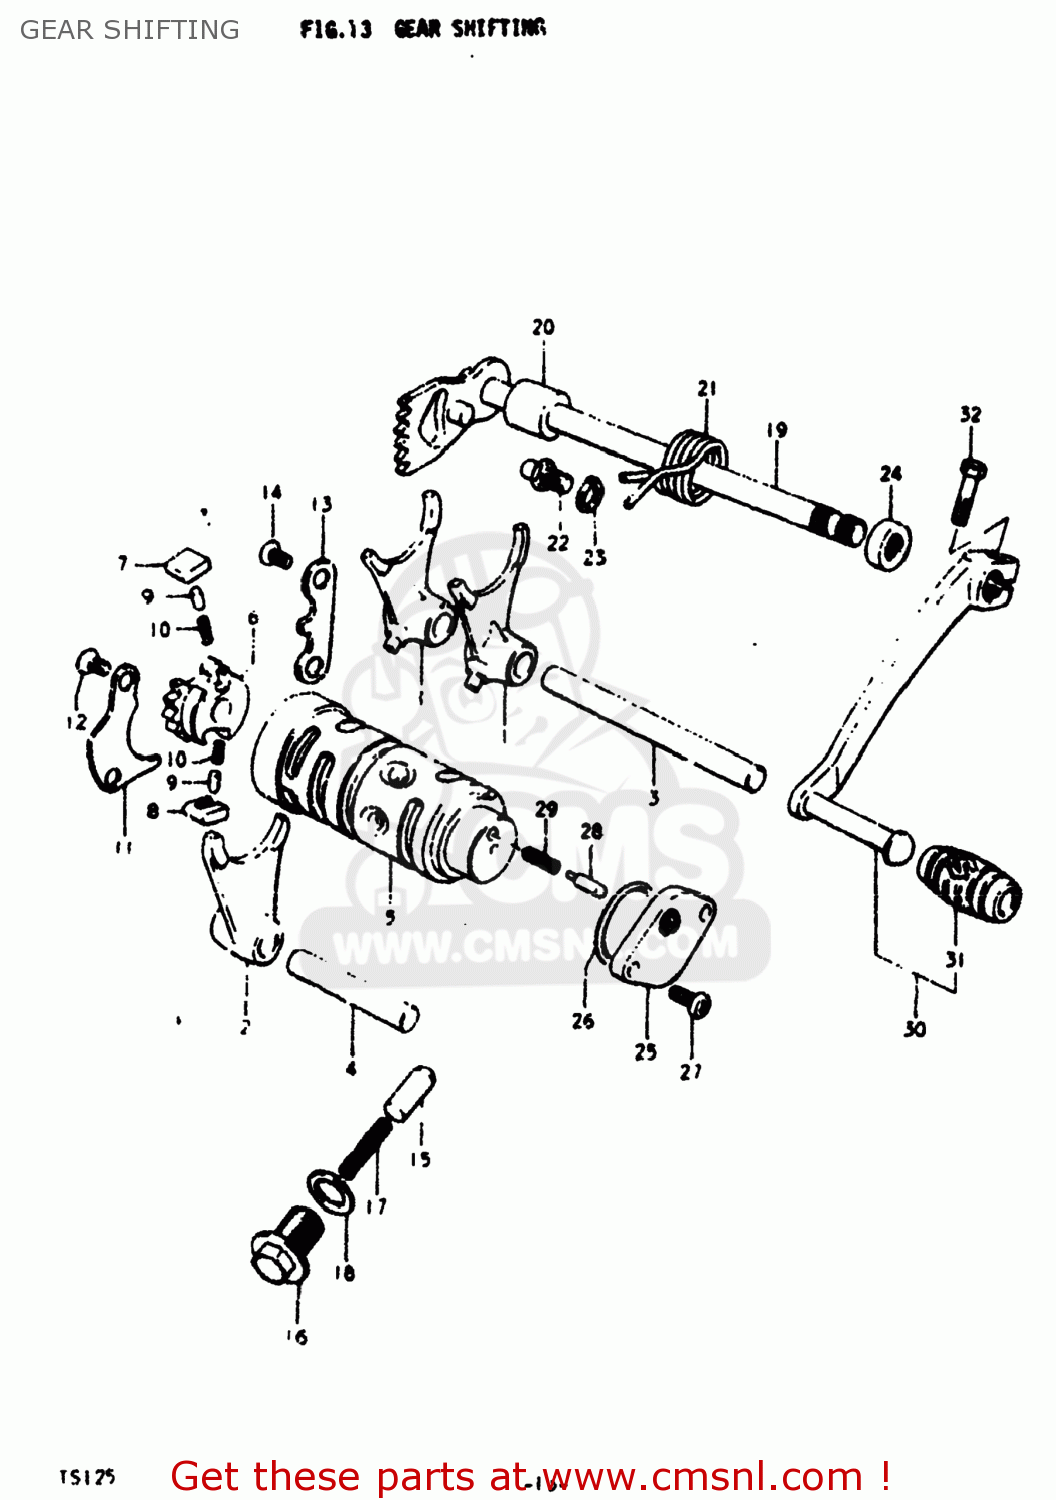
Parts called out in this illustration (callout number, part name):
1	FORK,GEAR SHIFT NO.1
2	FORK,GEAR SHIFT NO.2
3	SHAFT,GEAR SHIFT FORK
4	SHAFT,GEAR SHIFT FORK
5	CAM,GEAR SHIFT
6	RETAINER,GEAR SHIFT CAM
7	PAWL,GEAR SHIFT NO.1
8	PAWL,GEAR SHIFT NO.2
9	PIN(5X8)
10	SPRING
11	LIFTER,GEAR SHIFT PAWL
12	SCREW
13	GUIDE,GEAR SHIFTING CABLE
14	SCREW
15	STOPPER,GEAR SHIFTING
16	BOLT,GEAR SHAFT CAM STOPPER
17	SPRING
18	GASKET(14X19.2X2) (NAS)
19	SHAFT,GEAR SHIFT
20	SPACER(12X20X15.3)
21	SPRING
22	STOPPER,GEAR SHIFT CAM
23	WASHER
24	OIL SEAL
25	BODY,GEAR SHIFT SWITCH
26	O-RING (D:2.4 ID:26.2)
27	SCREW
28	PIN(5X15.5)
29	SPRING
30	LEVER ASSY,GEAR SHIFT
31	RUBBER,GEAR SHIFT PEDAL
32	BOLT
